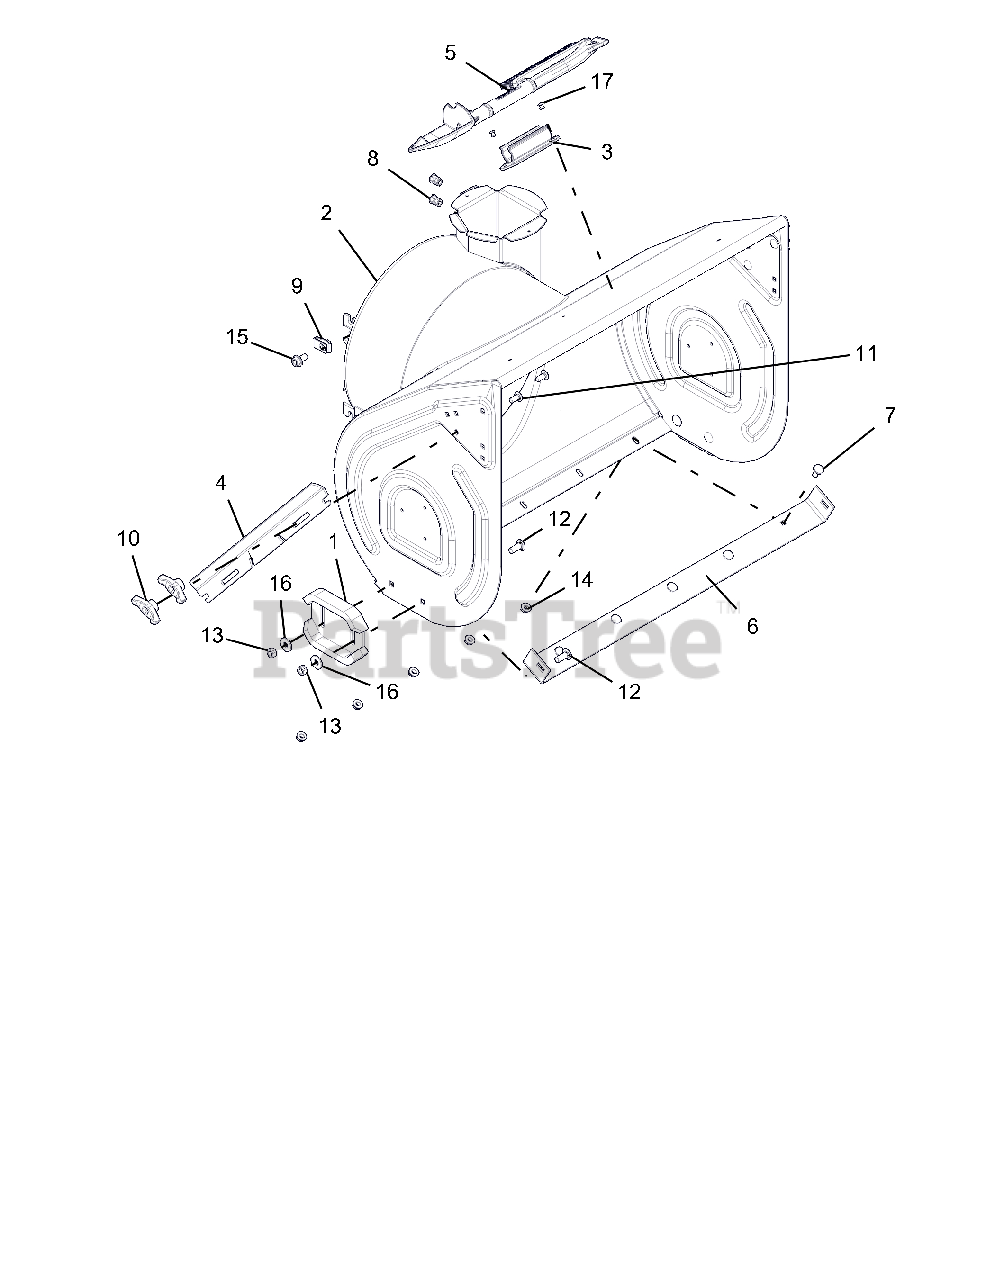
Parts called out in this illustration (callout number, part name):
1	RUNNER, SKID SHOE
2	BLOWER HOUSING W/DECAL 28"
3	MOUNT, SNOW CLEAN OUT
4	CUTTER, DRIFT
5	DEVICE, SNOW CLEAN OUT W/BRUSH
6	BLADE, SCRAPER-28"
7	BOLT, MODIFIED HEAD CARRIAGE
8	NUT, THREADED INSERT .38-16
9	NUT-RTNR .375-16X.37
10	KNOB,WING .31-18 UNC NYL/TALC
11	@BLT-RHDSSQNK .31-18X.75 G5YZ
12	@BLT-RDHDSHSQNK.38-16X1.0 G5YZ
13	@NUT-LK-CTR .38-16 YWZC
14	@NUT-LK-TOP-FLG .31-18 YWZC
15	BLT-SERHFWH .38-16X.75 YWZC
16	@WSHR-FL-STL.438X1.00X.083 YWZ
17	RVT-POP .187 YZ
